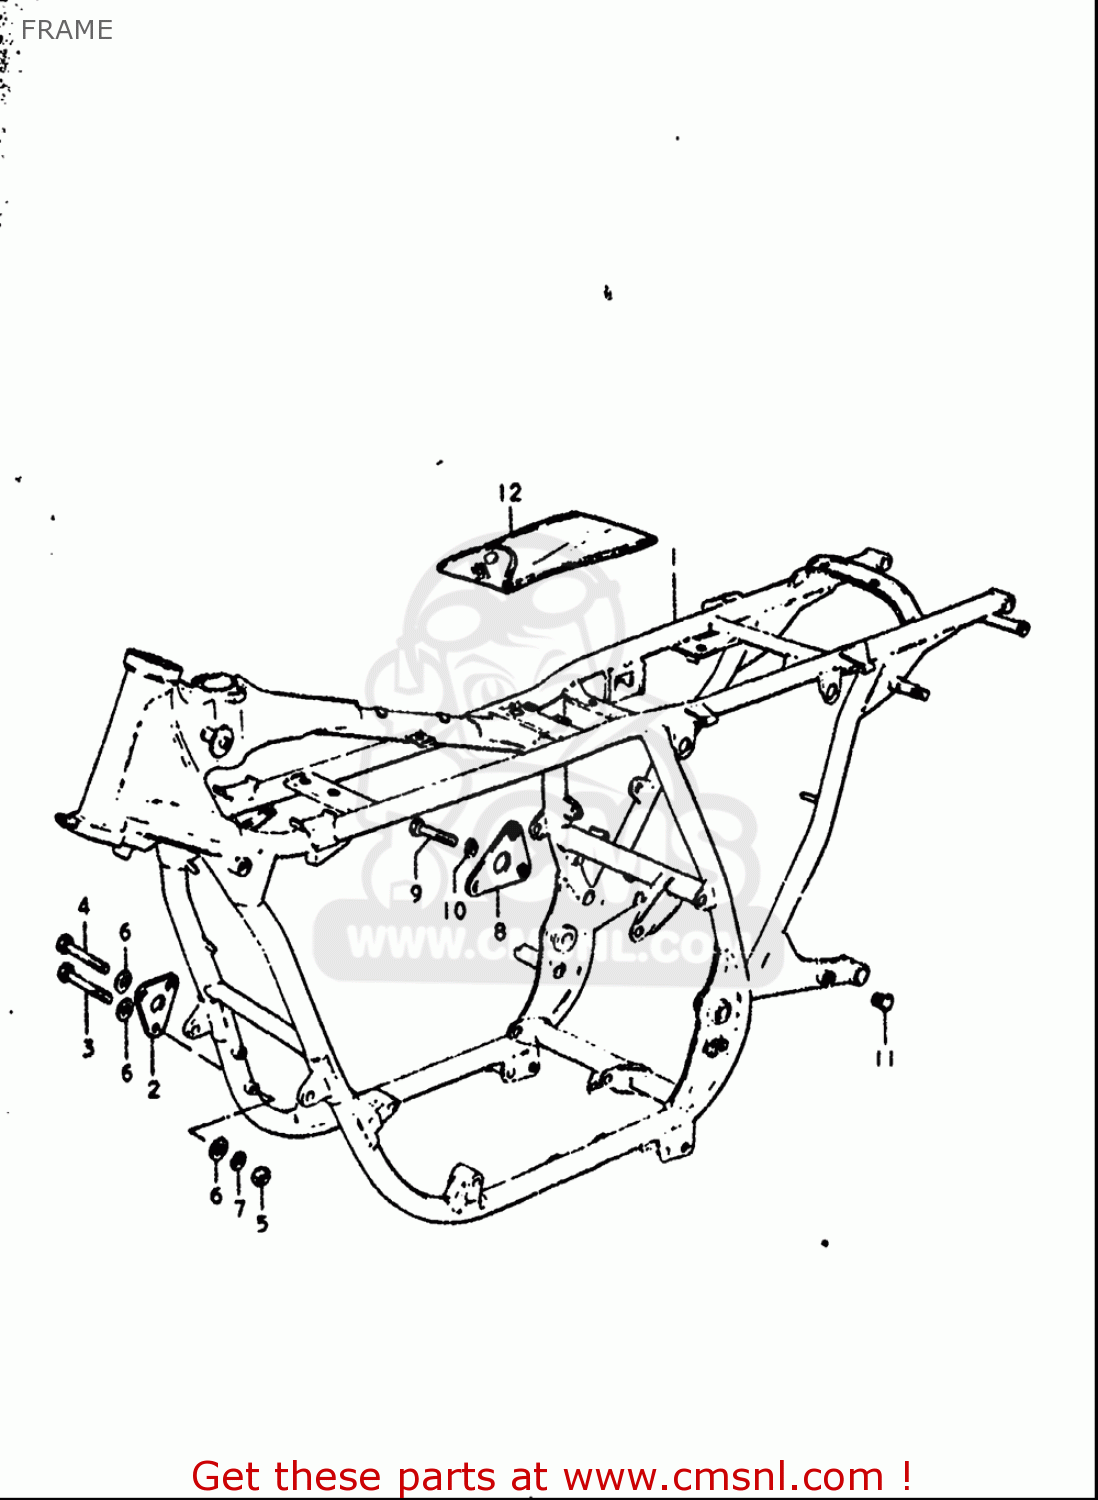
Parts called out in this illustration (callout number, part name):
3	BOLT
4	BOLT
5	NUT
6	WASHER
7	WASHER,LOCK
9	BOLT
10	WASHER,LOCK
11	CAP(OD:14)
12	TOOL ASSY
